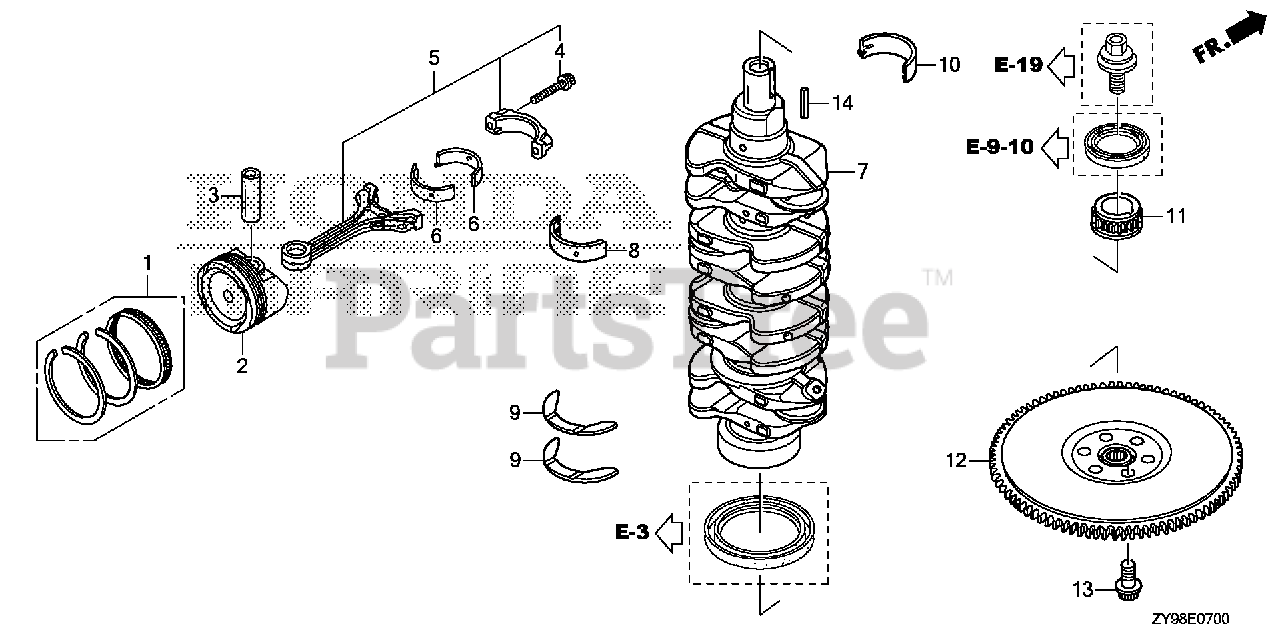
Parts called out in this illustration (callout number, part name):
1	RING SET, PISTON (STD)
1	RING SET, PISTON (0.25)
2	PISTON (STD)
2	PISTON (0.25)
3	PIN, PISTON
4	BOLT, CONNECTING ROD
5	ROD, CONNECTING
6	BEARING A, CONNECTING ROD (BLUE) (DAIDO)
6	BEARING B, CONNECTING ROD (BLACK) (DAIDO)
6	BEARING C, CONNECTING ROD (BROWN) (DAIDO)
6	BEARING D, CONNECTING ROD (GREEN) (DAIDO)
6	BEARING E, CONNECTING ROD (YELLOW) (DAIDO)
6	BEARING F, CONNECTING ROD (PINK) (DAIDO)
6	BEARING G, CONNECTING ROD (RED) (DAIDO)
7	CRANKSHAFT
8	BEARING B, MAIN (UPPER) (BLACK) (DAIDO)
8	BEARING C, MAIN (UPPER) (BROWN) (DAIDO)
8	BEARING D, MAIN (UPPER) (GREEN) (DAIDO)
8	BEARING E, MAIN (UPPER) (YELLOW) (DAIDO)
8	BEARING F, MAIN (UPPER) (PINK) (DAIDO)
8	BEARING G, MAIN (UPPER) (RED) (DAIDO)
8	BEARING H, MAIN (UPPER) (WHITE) (DAIDO)
9	WASHER, THRUST
10	BEARING B, MAIN (LOWER) (BLACK) (DAIDO)
10	BEARING C, MAIN (LOWER) (BROWN) (DAIDO)
10	BEARING D, MAIN (LOWER) (GREEN) (DAIDO)
10	BEARING E, MAIN (LOWER) (YELLOW) (DAIDO)
10	BEARING F, MAIN (LOWER) (PINK) (DAIDO)
10	BEARING G, MAIN (LOWER) (RED) (DAIDO)
10	BEARING H, MAIN (LOWER) (WHITE) (DAIDO)
11	SPROCKET, CAM CHAIN (23T)
12	FLYWHEEL *TBLACK* (BLACK)
13	BOLT (12MM)
14	KEY, SPECIAL
